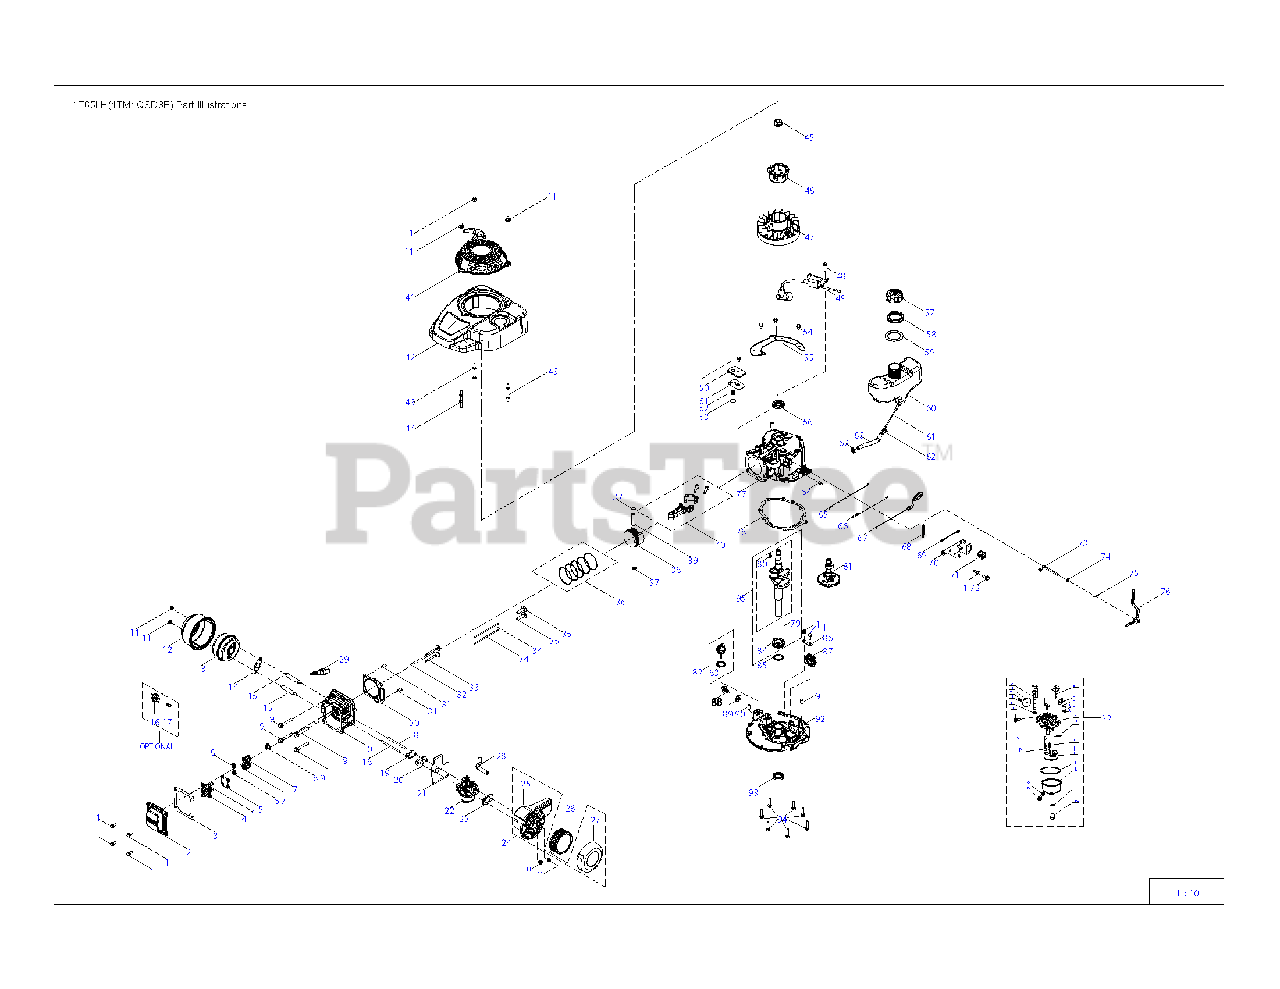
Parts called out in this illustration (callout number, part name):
1	BOLT M6-1 x 14 GR8.8
2	VALVE COVER
3	VALVE COVER GASKET
4	ROCKER ARM ASSEMBLY
5	PUSH ROD GUIDE
6	VALVE SPRING RETAINER
7	VALVE SPRING
8	INTAKE VALVE SEAL
9	SCREW M8 x 54 GR10
10	CYLINDER HEAD
11	HEX NUT
12	MUFFLER SHIELD
13	MUFFLER ASSEMBLY
14	MUFFLER GASKET
15	STUD M6-1 x 76
16	SPARK ARRESTOR
17	SCREW M3.5 x 9.5
18	CARBURETOR STUD-M6 x 87
19	CARBURETOR INSULATOR GASKET
20	CARBURETOR INSULATOR
21	CARBURETOR GASKET
22	CARBURETOR ASSEMBLY
23	AIR FILTER BASE GASKET
24	AIR FILTER ASSEMBLY
25	AIR FILTER BASE
26	PAPER AIR FILTER
27	AIR FILTER COVER
28	BREATHER HOSE
29	SPARK PLUG
30	CYLINDER HEAD GASKET
31	DOWEL PIN
32	INTAKE VALVE
33	EXHAUST VALVE
34	PUSH ROD
35	TAPPET (LIFTER)
36	PISTON RING SET
37	SNAP RING-PISTON PIN
38	PISTON
39	PISTON PIN
40	CONNECTING ROD ASSEMBLY
41	STARTER RECOIL ASSEMBLY
42	ENGINE SHROUD ASSEMBLY
43	STUD M6 x 75
44	STUD M6 x 73
45	FLYWHEEL NUT
46	START CUP
47	FLYWHEEL
48	BOLT M6-1 x 25 GR8.8
49	IGNITION COIL
50	BREATHER COVER PLATE
51	BREATHER COVER GASKET
52	BREATHER VALVE SPRING
53	BREATHER VALVE
54	BOLT M6-1 x 10 GR8.8
55	COVER SHIELD PLATE
56	UPPER CRANKSHAFT SEAL
57	FUEL CAP ASSEMBLY
58	FUEL TANK NUT
59	FUEL TANK UPPER GROMMET
60	FUEL TANK
61	FUEL FILTER
62	HOSE CLAMP
63	FUEL HOSE
64	Control Bracket Spacer
65	THROTTLE LINKAGE
66	THROTTLE LINKAGE SPRING
67	CHOKE CONTROL
68	GOVERNOR SPRING
69	IGNITION SWITCH
70	COMPONENT BRACKET
71	IGNITION SWITCH
72	BOLT M6-1 x 35 GR8.8
73	GOVERNOR ARM SHAFT
74	GOVERNOR SEAL
75	COTTER PIN
76	GOVERNOR ARM ASSEMBLY
77	CRANKCASE
78	CRANKCASE COVER GASKET
79	CRANKSHAFT ASSEMBLY
80	FLYWHEEL KEY
81	CAMSHAFT ASSEMBLY
82	DIPSTICK ASSEMBLY
83	DIPSTICK O-RING
84	CRANKSHAFT TIMING GEAR
85	THRUST WASHER
86	GOVERNOR GEAR MOUNTING PLATE
87	GOVERNOR GEAR/SHAFT ASSEMBLY
88	OIL DRAIN PLUG
89	WASHER
90	DOWEL PIN
91	DOWEL PIN
92	CRANKCASE COVER
93	LOWER CRANKSHAFT SEAL
94	BOLT-M6-1 x 28 GR8.8
